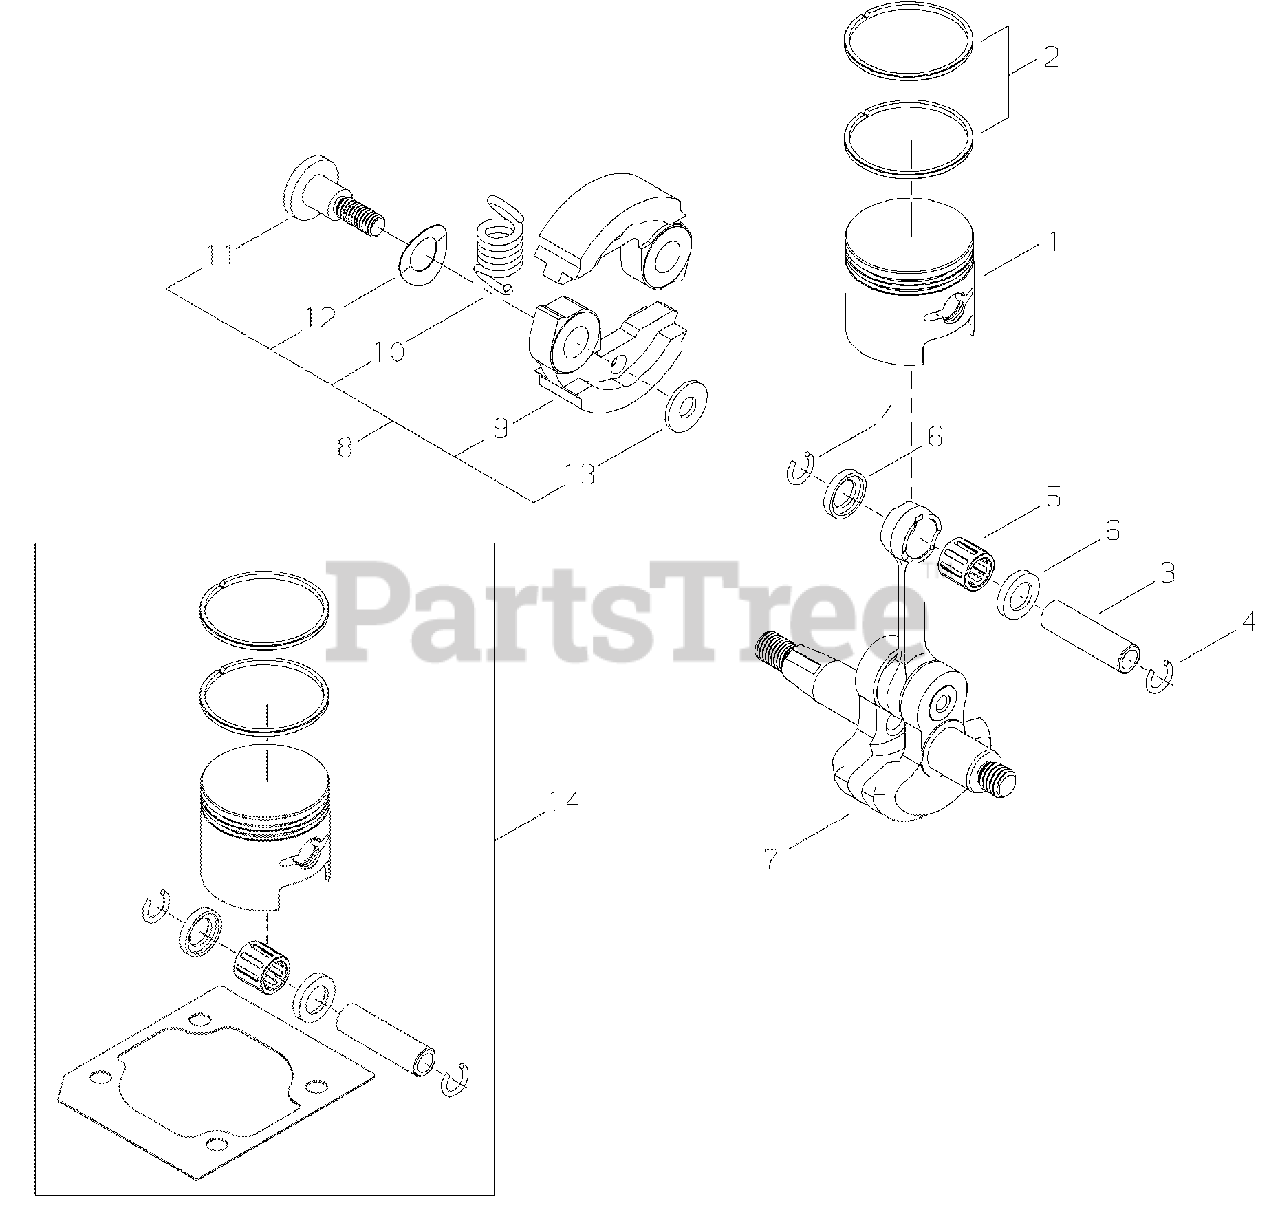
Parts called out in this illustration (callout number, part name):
1	PISTON
2	RING, PISTON
3	PIN, PISTON
4	RING, RETAINING
5	BEARING, NEEDLE - 8
6	SPACER, PISTON
7	CRANKSHAFT ASSY
8	CLUTCH ASSY
9	SHOE, CLUTCH
10	SPRING, CLUTCH
11	BOLT, CLUTCH
12	WASHER - SPRING
13	WASHER - 6
14	PISTON KIT
